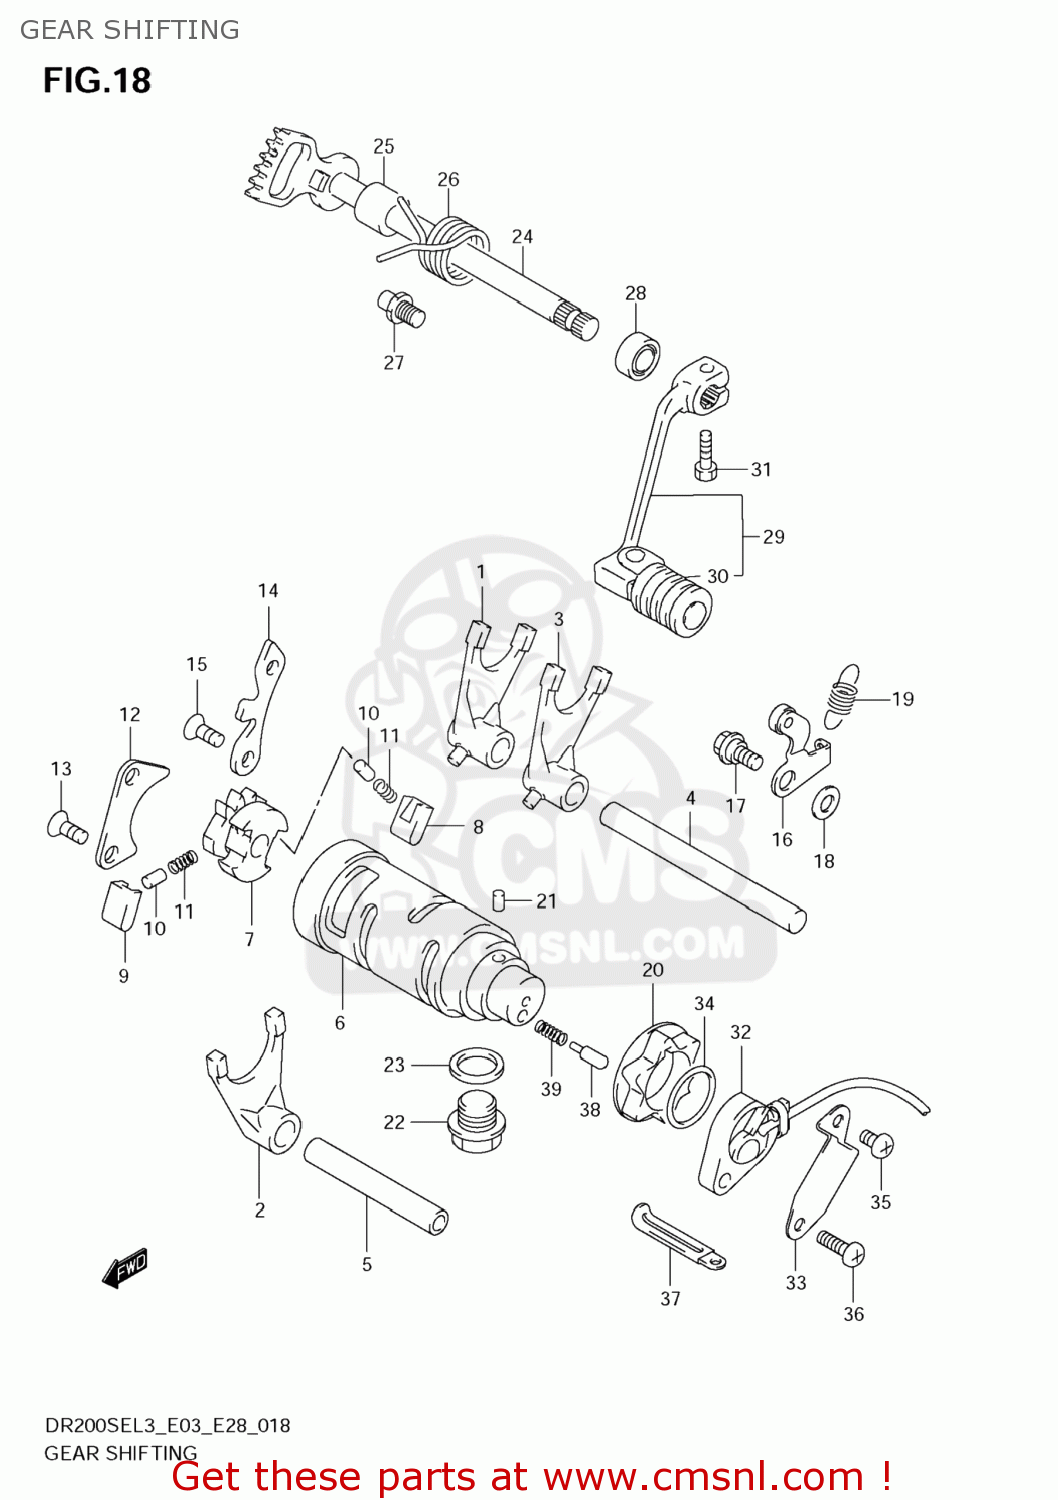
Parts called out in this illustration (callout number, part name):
1	FORK,GEAR SHIFT NO.1
2	FORK,GEAR SHIFT NO.2
3	FORK,GEAR SHIFT NO.3
4	SHAFT,GEAR SHIFT FORK(L:109)
5	SHAFT,GEAR SHIFT FORK NO.2
6	CAM,GEAR SHIFT
7	GEAR,GEAR SHIFT CAM DRIVEN
8	PAWL,GEAR SHIFT NO.1
9	PAWL,GEAR SHIFT NO.2
10	PIN(5X8)
11	SPRING
12	LIFTER,GEAR SHIFT POLE
13	SCREW(6X12)
14	GUIDE,GEAR SHIFT CAM
15	SCREW(6X12)
16	STOPPER,GEAR SHIFT CAM
17	BOLT(6X14.6)
18	WASHER
19	SPRING
20	PLATE,GEAR SHIFT CAM STOPPER
21	PIN
22	PLUG(14X12)
23	GASKET(13.8X18.8X4.8) (NAS)
24	SHAFT,GEAR SHIFT
25	SPACER(12X20X15.3)
26	SPRING
27	STOPPER,GEAR SHIFT ARM
28	SEAL,OIL (12X22X9)
29	LEVER ASSY,GEAR SHIFT
30	RUBBER,GEAR SHIFT PEDAL
31	BOLT
32	BASE ASSY,NEUTRAL SW TERMINAL
33	PROTECTOR,GEAR SHIFT SW
34	O RING(D:2.4,ID:21.8)
35	SCREW
36	SCREW
37	CLAMP(L:45)
38	PIN(5X15.5)
39	SPRING
